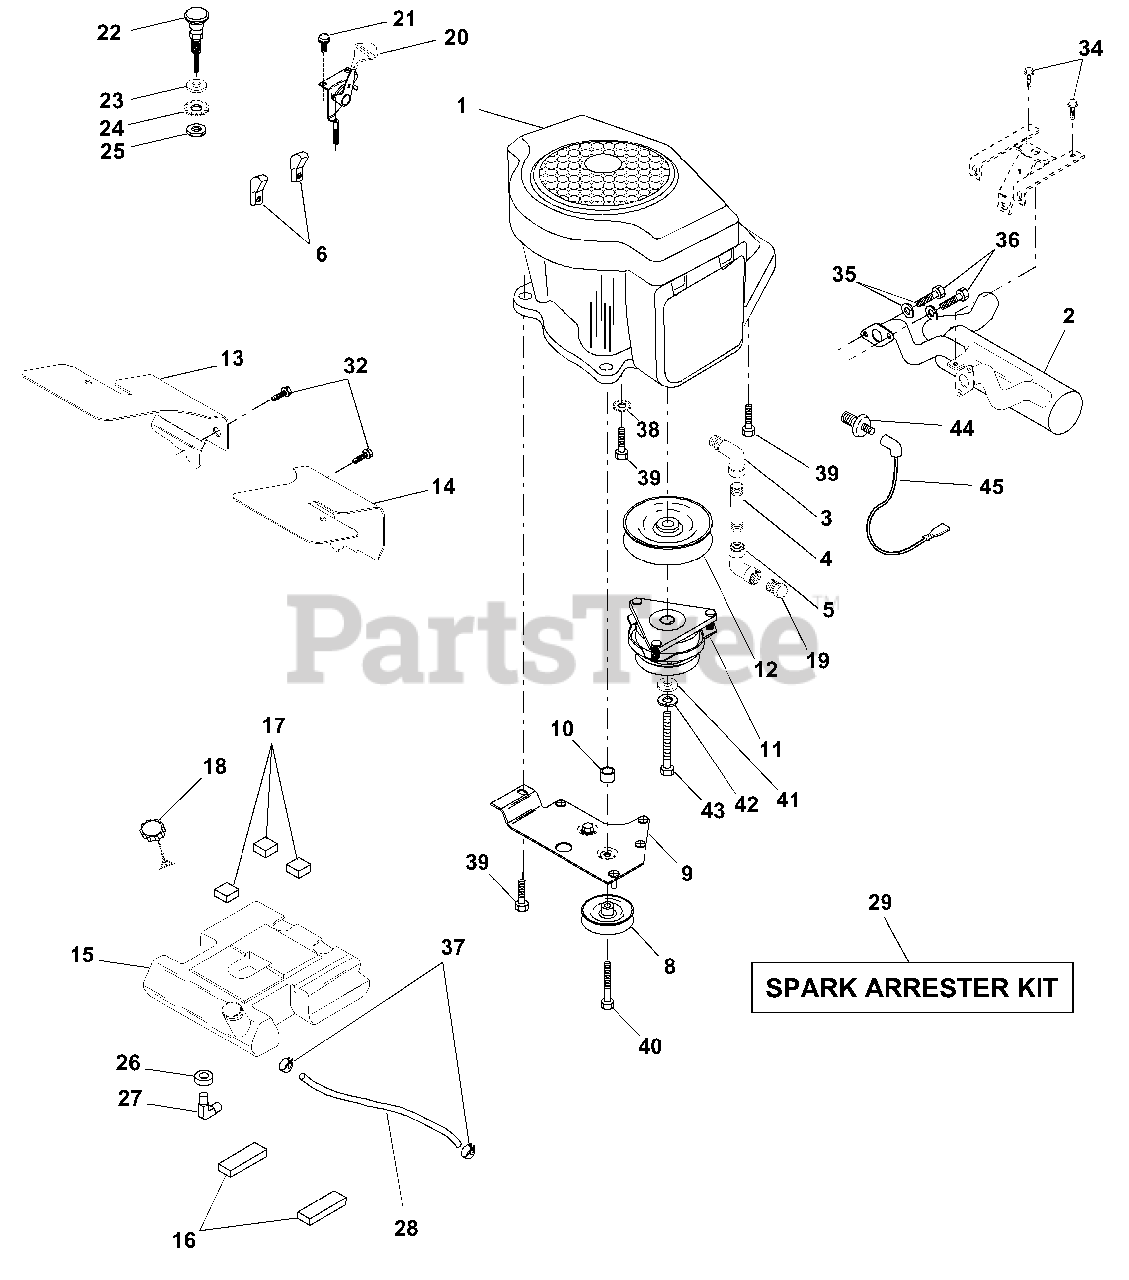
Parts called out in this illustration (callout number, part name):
1	Engine Kohler,
2	Muffler Asm Kohler VGT
3	Elbow Street 3/8 NPT
4	Nipple Pipe 3/8 NPT X 3 - 1/2
5	Elbow STD 90 Degree 3/8 - 18 NPT
6	Clamp Tube Double Engine
8	Pulley V-Idler
9	Stop Keeper Asm VGT
11	Clutch Electric
12	Pulley Engine VGT Elect Clutch
13	Baffle Air LH Koh VGT
14	Baffle Air RH Koh VGT
15	Tank Fuel W/Sym Vented
16	Pad Spacer
17	Pad Spacer
18	Cap Asm Fuel W/Sym Vented
19	Plug Oil Drain
20	Control Throttle
21	Screw Hex Thd Cut 1/4 - 20 X 5/8
22	Control Choke
23	Washer 13/32 X 13/16 x 16 Ga
24	Washer Ext Tooth 3/8
25	Nut Fin Hex 3/8 - 24 UNF
26	Bushing
27	Stem Tank Fuel
28	Fuel Line
29	Spark Arrester Kit
32	Screw Thdrol 5/16 - 18 X 1/2
34	Screw Thd Cut 1.4 - 20 x 1/2
35	Washer Lock 5/16
36	Screw Hex 5/16 - 16 UNC X 3/4
37	Clamp Hose
38	Lockwasher Ext Tooth 3/8
39	Screw Thdrol 3/8 - 16 X 1 - 1/2 TT
40	Screw Thdrol 3/8 - 16 X 3 - 1/4
41	Washer 1-1/2 OD X 15/32 ID X .250
42	Washer Lock 7/16
43	Bolt Hex 7/16-20 X 4-1/4 Ga 5
44	Switch Oil Sentry Kohler
45	Wire Lead Sentry Kohler
